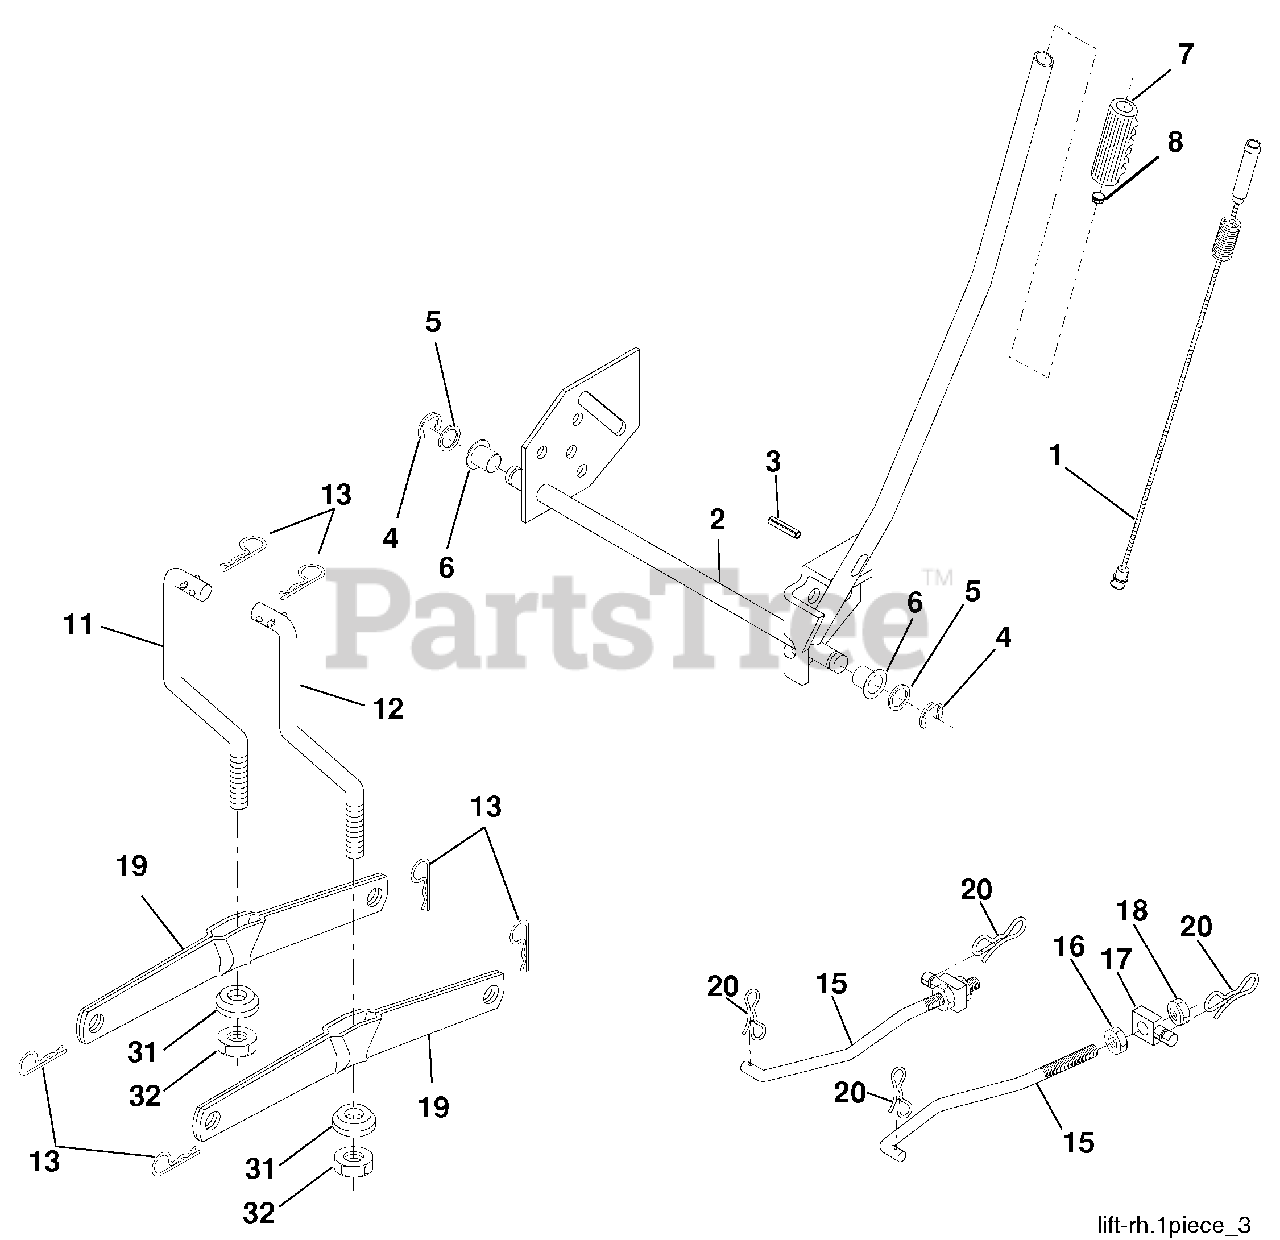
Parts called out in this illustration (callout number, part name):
1	Wire Asm Inner/Sprg W/plunger
2	Shaft Asm Lift RH w/Inf
3	Pin Groove 5/16 Dia x 1.875
4	E Ring #5133-62
5	Washer 21/32 x 1 x 21 Ga.
6	Bearing Nylon Blk 629 Id
7	Grip Handle
8	Button Plunger
11	Link Lift LH Fixed Length
12	Link Lift RH Fixed Length
13	Retainer Spring
15	Link Front
16	Nut Jam Hex 1/2-13 unc
17	Trunnion
18	Nut Lock W/Wsh 1/2-13 unc
19	Arm Suspension Rear
20	Pin Cotter 7/16 Bow Tie Lock
31	Bearing Pvt Lift
32	Nut Crownlock 3/8 - 24
